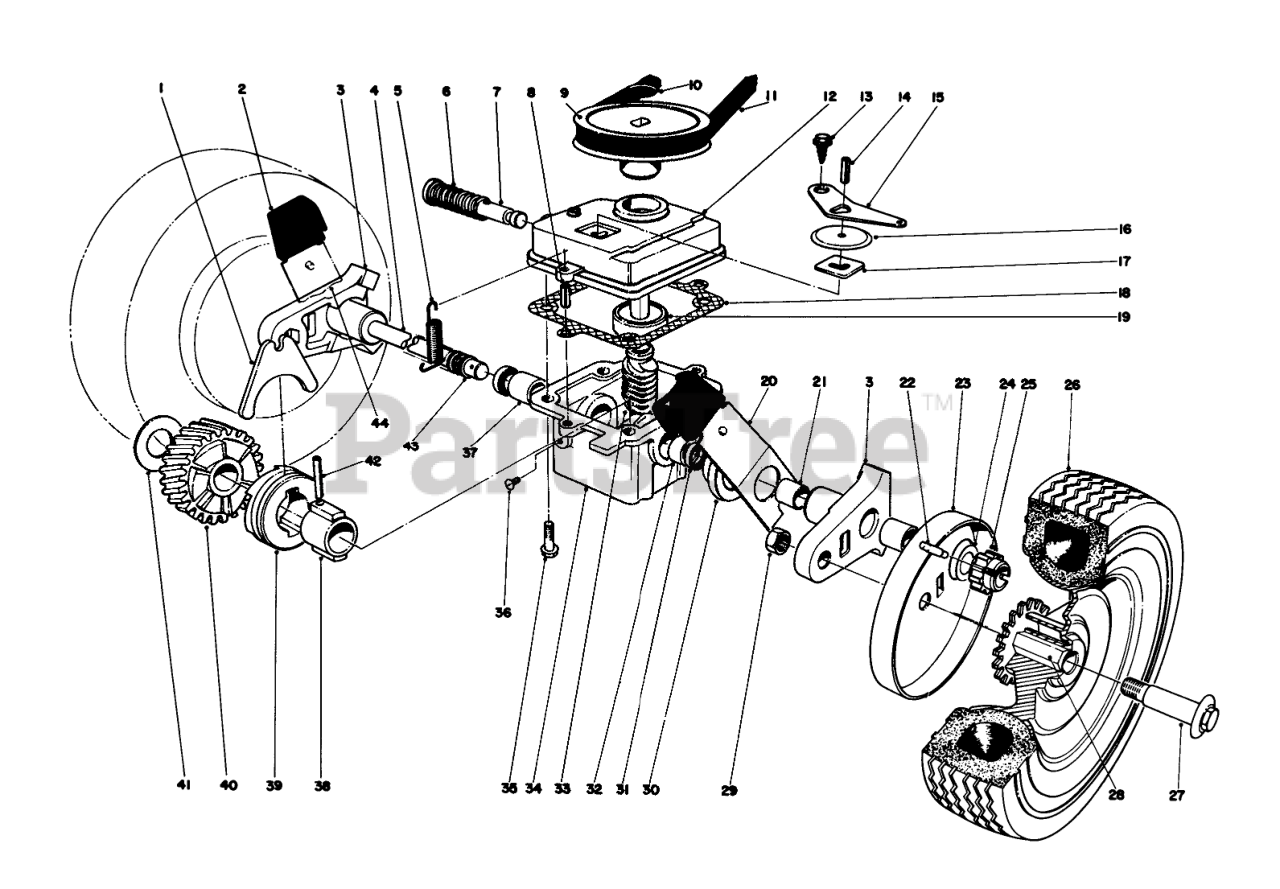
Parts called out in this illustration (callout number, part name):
1	SHIFTER FORK
2	KNOB-ARM
3	Pivot Arm (Incl. Ref. 21)
4	Drive Shaft
5	TENSION SPRING
6	SPRING
7	Shift Rod
8	3/16 X 1/2 ROLL PIN
9	PULLEY
10	PUSH-ON 93-3236
11	V BELT
12	Cover Gear Case
13	Screw
14	PIN-ROLL
15	SHIFTER ARM
16	TRANS DUST COVER
17	LATCH PLATE
18	GASKET
19	Bearing
20	SPRING ARM ASM SP LH
21	BUSHING
22	PIN-GROOVED
23	WHEEL COVER
24	WASHER-THRUST
25	Pinion
26	Wheel & Tire Assembly (Incl. Ref. #28)
28	WHEEL BUSHING
29	Nut
30	End Cap
31	Seal
32	Bushing
33	Worm Shaft & Gear (Incl. Ref. #40)
34	Gear Case (Incl. Ref. #31-32 & 37)
35	Screw
36	NYLON SCREW
37	Bushing
38	SLEEVE
39	CLUTCH JAW
40	Helical Gear
41	THRUST WASHER
42	COIL PIN
43	COVER-SHAFT, DRIVE
44	SPRING ARM ASM SP RH
